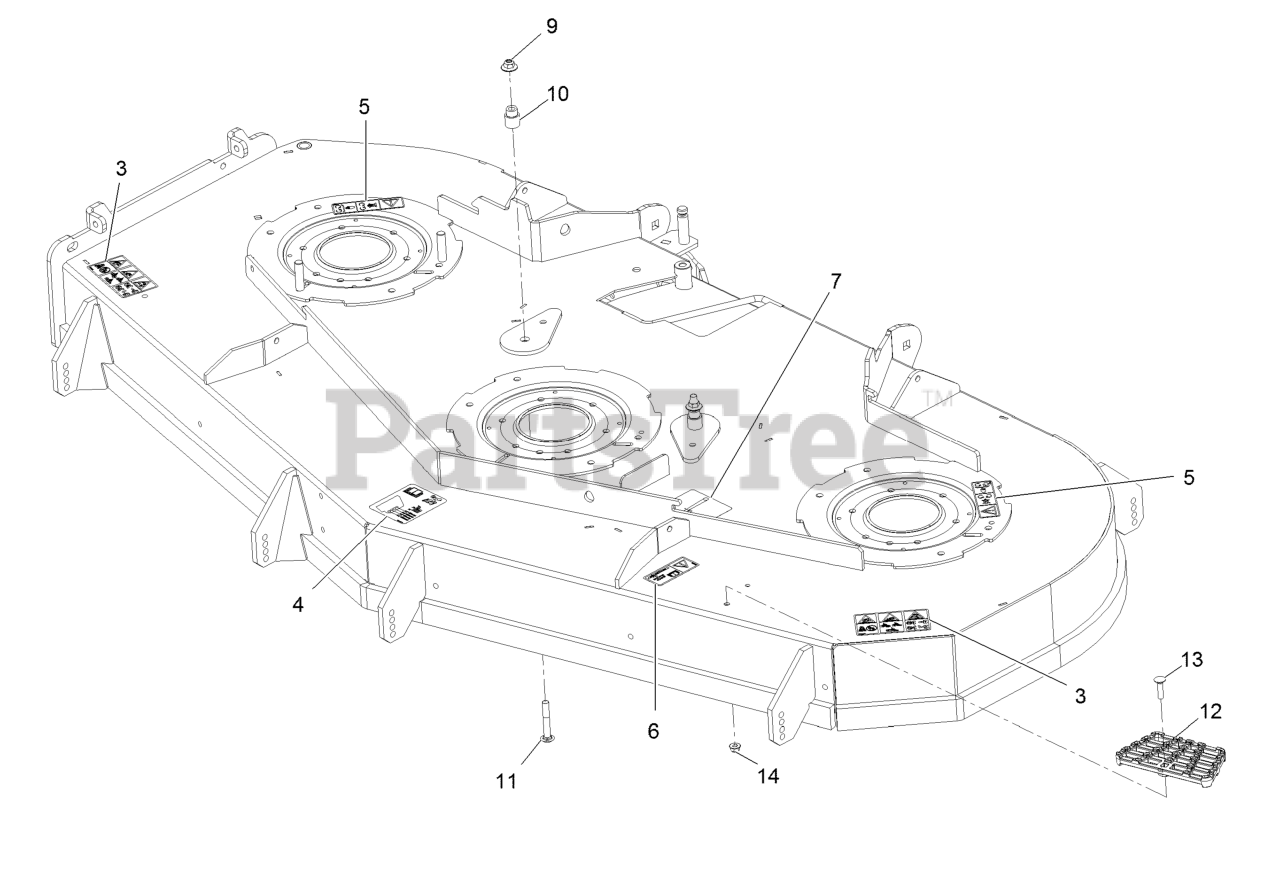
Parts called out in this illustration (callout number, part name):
3	Decal-Danger Thrown Objects
4	Decal-Roller, Anti-Scalp
5	Decal-Cover, Missing
6	Decal-Bolt Torque
7	Decal-Belt Routing
9	Nut-Flange, NI
10	Bushing, Idler
11	Screw-CARR
12	Step-Deck
13	Screw-CARR
14	Nut-HF, NI
